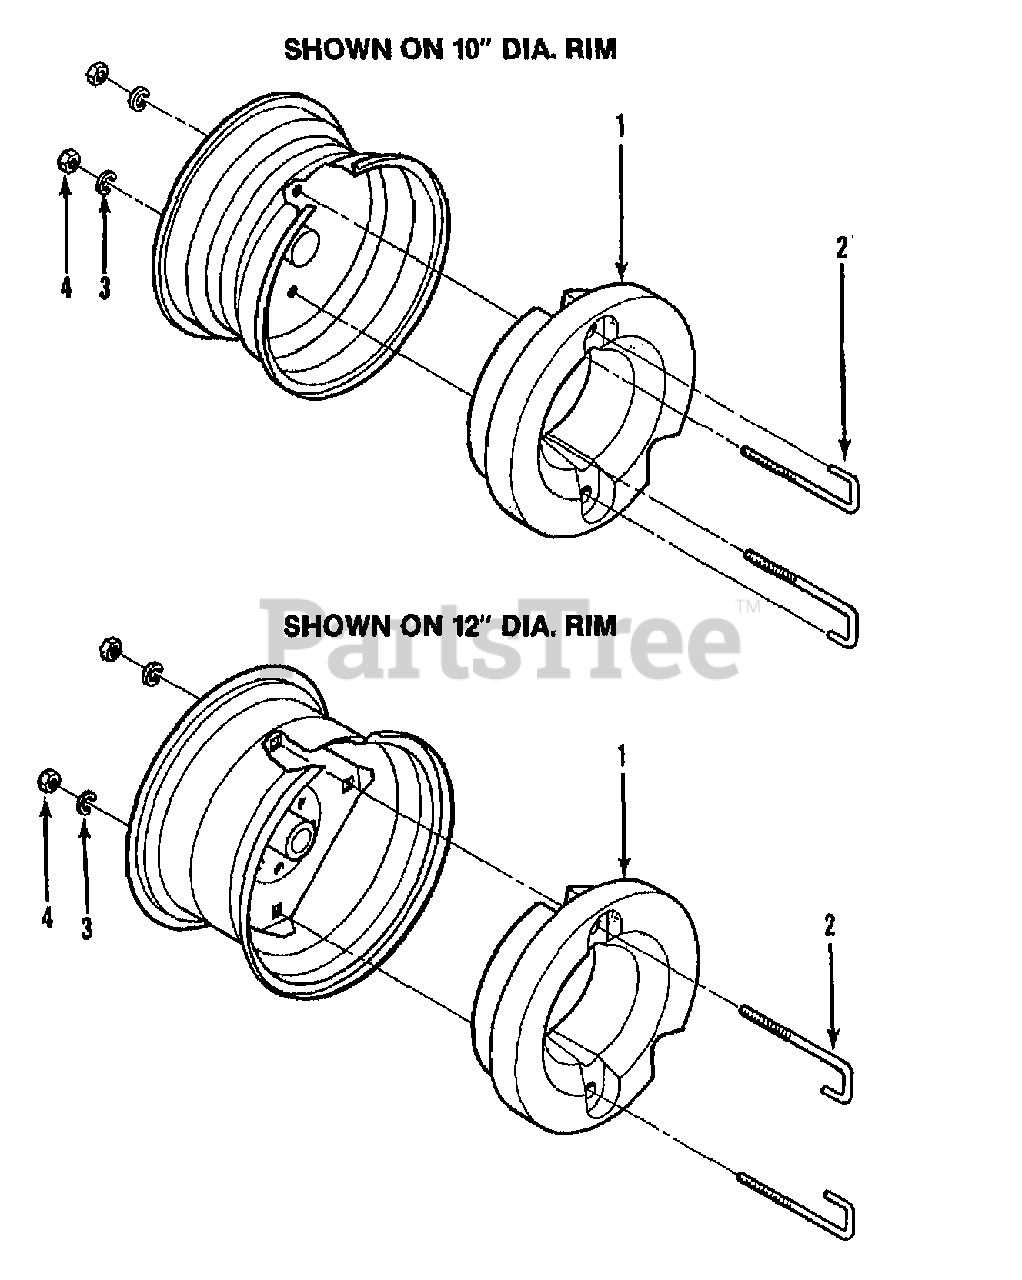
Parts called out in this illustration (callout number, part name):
1	WHEEL WEIGHT
2	HOOK BOLT
2	SCR-HOOK
3	LOCK WASHER
4	HEX NUT
